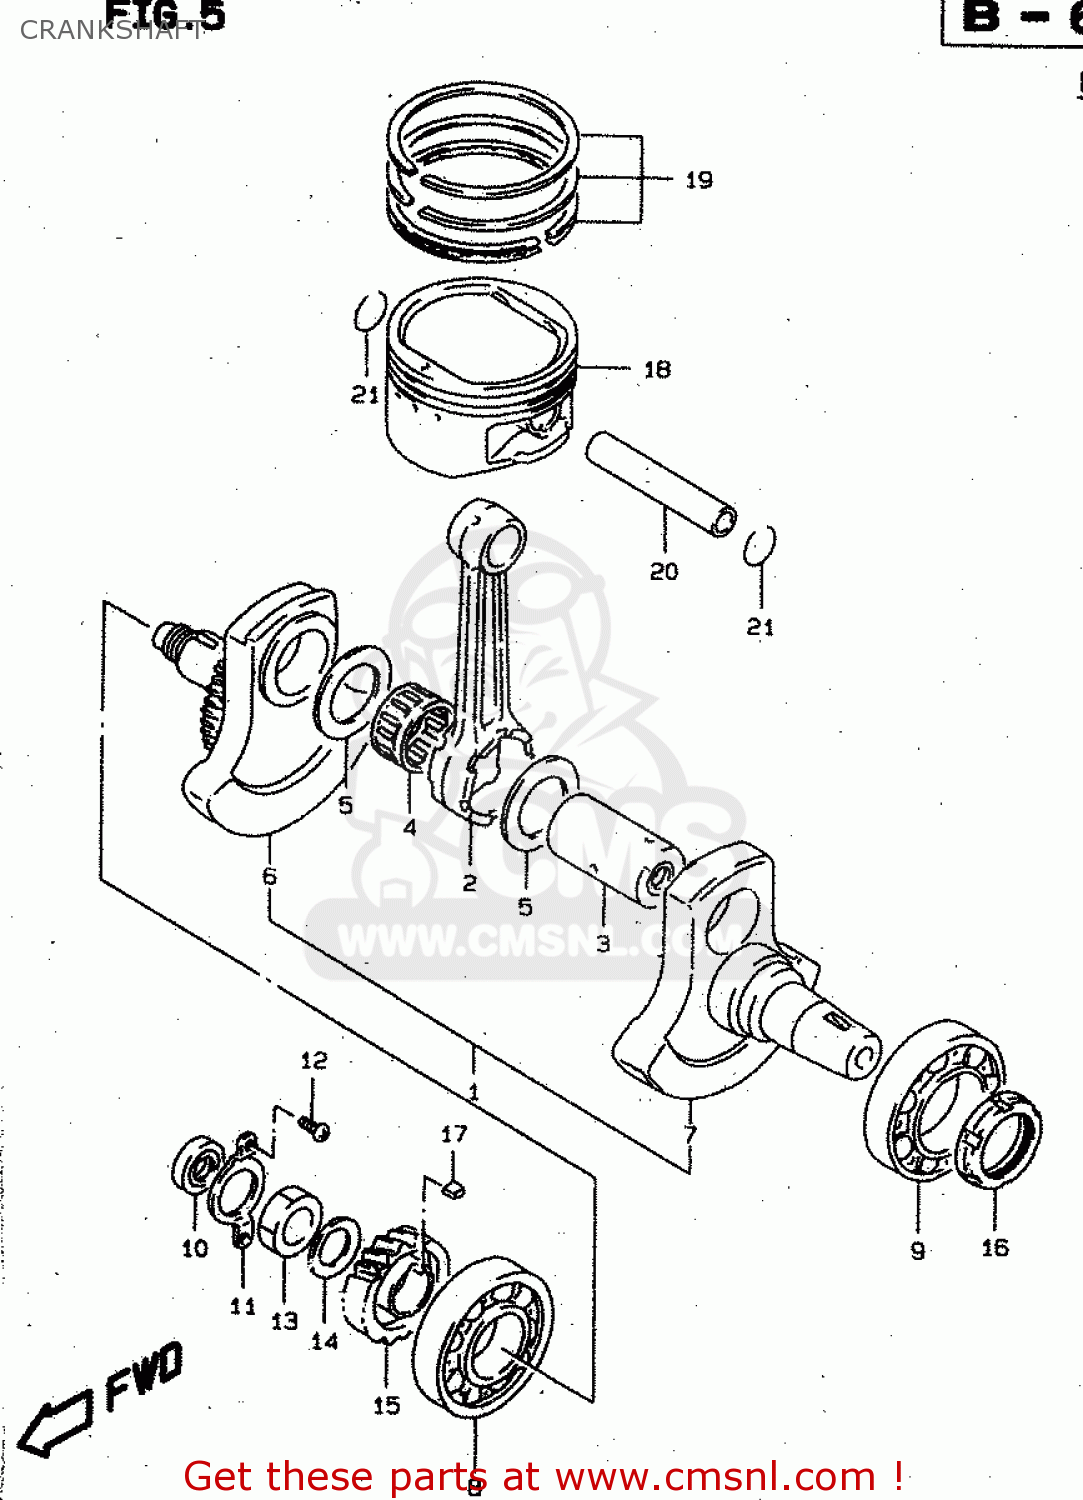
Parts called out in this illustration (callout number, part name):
1	CRANKSHAFT SET
2	CONNECTING ROD
3	PIN,CRANK
4	BEARING 37X47X25
5	WASHER(37X55X1)
6	CRANKSHAFT SET,R
7	CRANKSHAFT,L
8	BEARING(40X80X18)
9	BEARING(45X85X19)
10	SEAL,OIL(16X30X6)
11	RETAINER,CRANKSHAFT BEARING,R
12	SCREW
13	NUT (20MM)
14	WASHER
15	GEAR,PRIMARY DRIVE(NT:28)
16	NUT,CRANKSHAFT BRG,L
17	KEY
18	PISTON
19	RING SET,PISTON
20	PIN,PISTON
21	CIRCLIP
